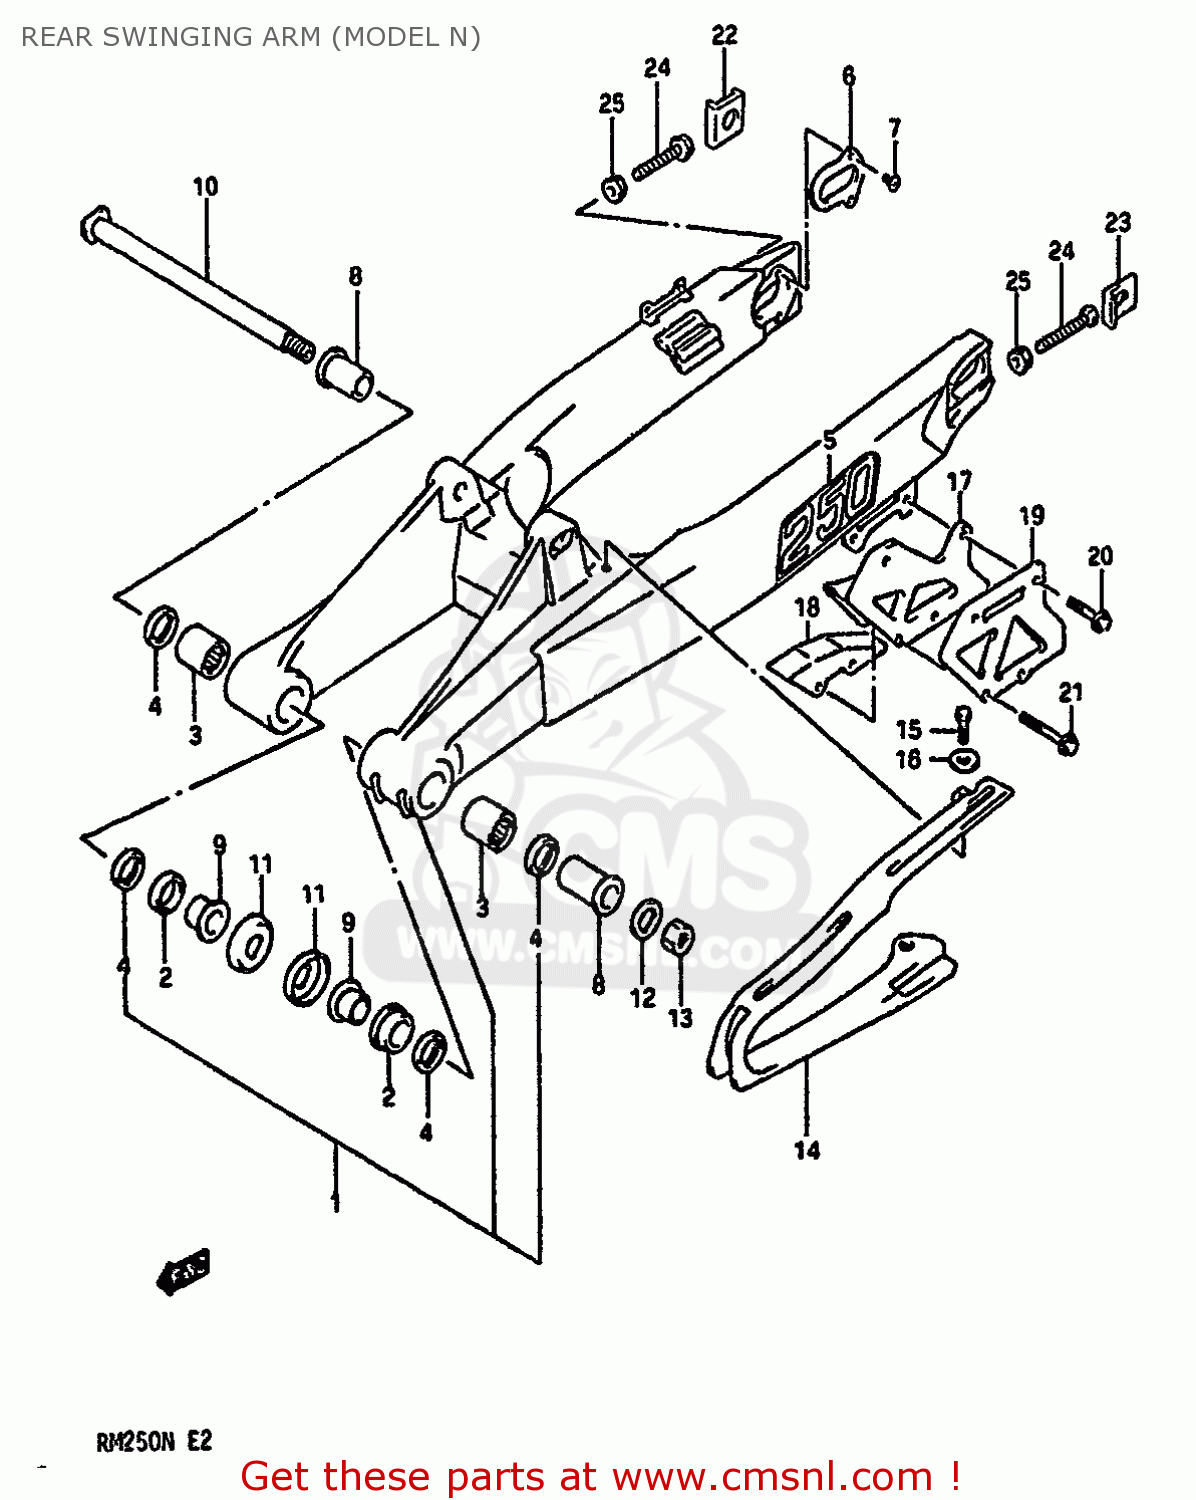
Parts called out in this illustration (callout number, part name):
1	SWING ARM ASSEMBLY,REAR
2	BUSHING,SWGARM PIVOT
3	BEARING(22X29X30)
4	SEAL,OIL(22X29X4)
5	EMBLEM,SWINGINGARM
6	PLATE,SWING ARM,REAR
7	SCREW
8	SPACER,REAR SWING ARM
9	SPACER,SWGARM PIVOT INNER
10	SHAFT,RR SWINGINGARM PIVOT
11	COVER,SWINGINGARM PIVOT
12	WASHER
13	NUT
14	BUFFER,CHAIN TOUCH DEFENSE
15	BOLT
16	WASHER
17	GUIDE,CHAIN
18	DEFENSE,CHAIN GUIDE
19	PLATE,CHAIN GUIDE,OUTER
20	BOLT
21	SCREW(6X40)
22	BOLT
23	BOLT
24	BOLT
25	NUT
26	NUT
27	WASHER,CHAIN ADJUSTER
28	BOLT
29	NUT
